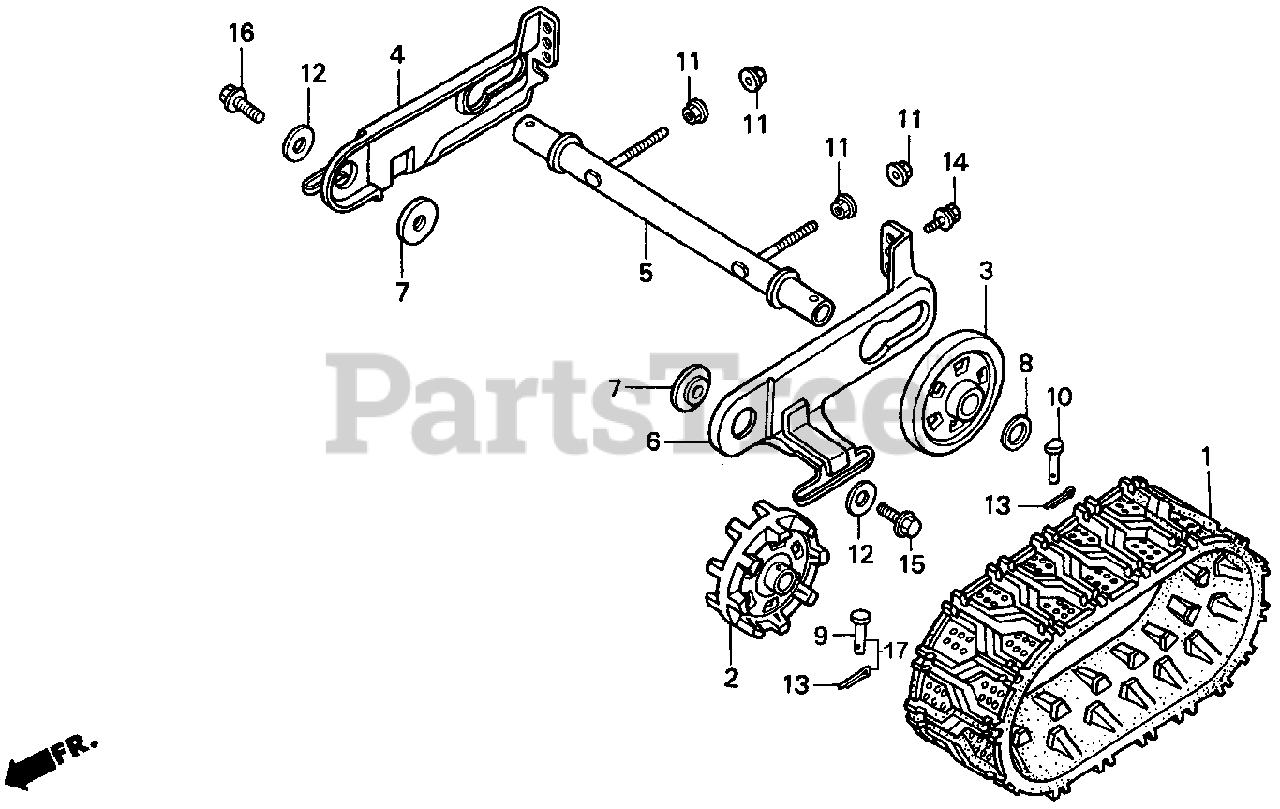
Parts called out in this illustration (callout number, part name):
1	CRAWLER (12-60X16B-503)
2	SPROCKET, CRAWLER
3	ROLLER, CRAWLER
4	PLATE, R. CRAWLER GUIDE
5	PIPE, CRAWLER
6	PLATE, L. CRAWLER GUIDE
7	WASHER, WHEEL SHAFT
8	WASHER, PLAIN (22MM)
9	PIN (6.2X38)
11	NUT, FLANGE (10MM)
12	WASHER, FLAT (10MM)
13	PIN, COTTER (3.0X18)
14	BOLT, FLANGE (8X16)
15	BOLT, FLANGE (10X20)
16	BOLT, FLANGE (10X25)
